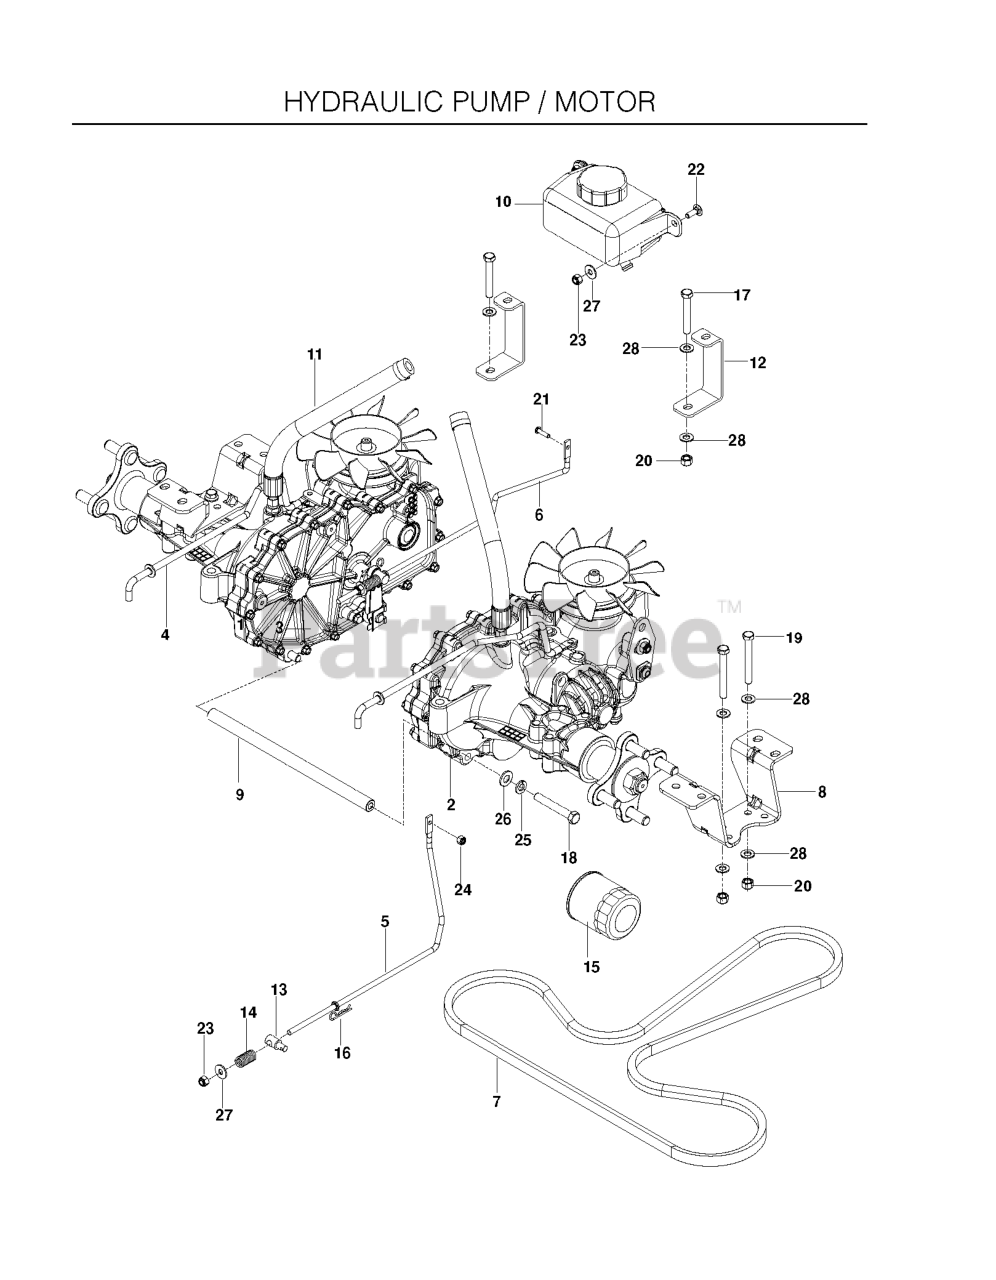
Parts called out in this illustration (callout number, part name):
1	HG_TRANS, ZT-2800 RT
2	HG_TRANS, ZT-2800 LEFT
3	ROD, BYPASS, RT
4	ROD, BYPASS, LT
5	LINKAGE, BRAKE RT
6	LINKAGE.BRAKE.LT
7	BELT, EZT HYDRO
8	EZT MOUNT, REAR, BLACK
9	SPACER TUBE, EZT, 11.08
10	HG_EXPANSION TANK W/CAP 71354
12	SUPPORT.FRONT.TRANS.BLACK.
13	BRAKE SWIVEL
15	HG_FILTER, ZT4800 52114
16	HAIRPIN #2
18	HCS 3/8C X 2 1/2
19	HCS 5/16C X 2-3/4
20	NUT 5/16 NYLOC
21	SCR #10-24 X 3/4
22	RHSNB 1/4C X 3/4
23	NUT.1/4-20.HEX.NYLOC.ZD
24	NUT 10-24 NYLOC
25	SLW 3/8 STD
26	WASHER 3/8 SAE FLAT
27	WASHER 1/4 FLAT
28	FLAT WASHER 5/16 SAE
